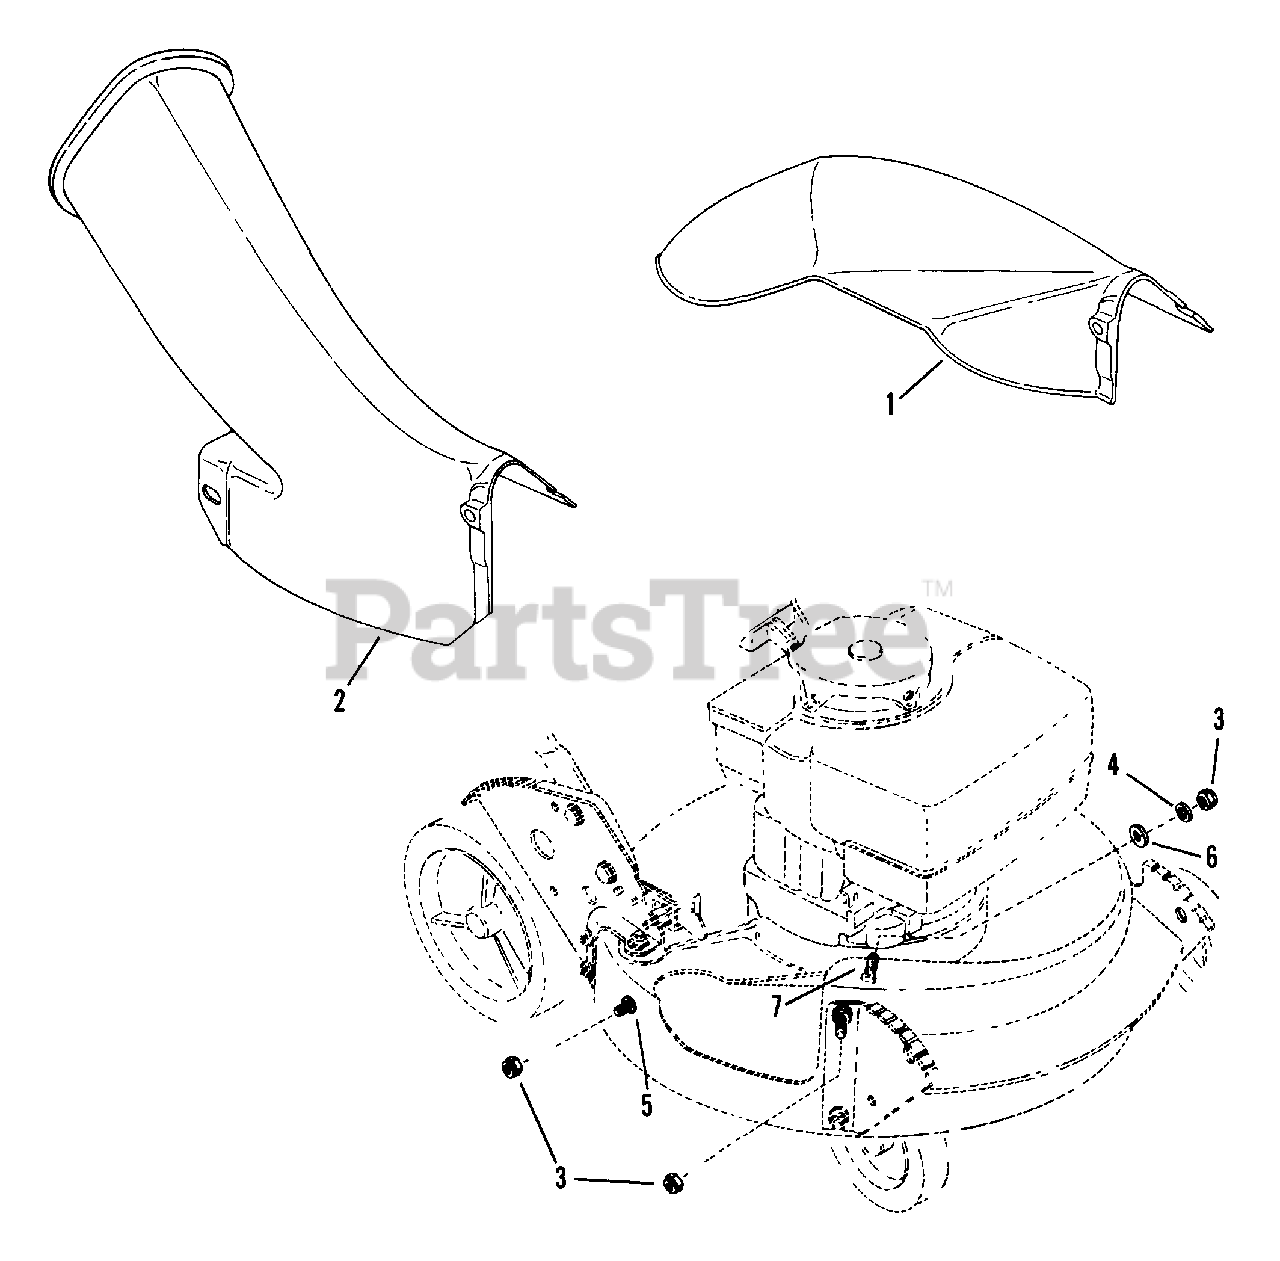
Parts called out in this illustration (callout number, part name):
1	CHUTE, Side
2	ADAPTER, Grass Bag Deck
3	NUT, 5/16-18 Hex Flange Lock
4	WASHER, 5/16 Flat
5	RETAINER, 5/16 Bolt
6	WASHER, 5/16 Flat
7	BOLT, 5/16-18 x 3/4" Carriage
